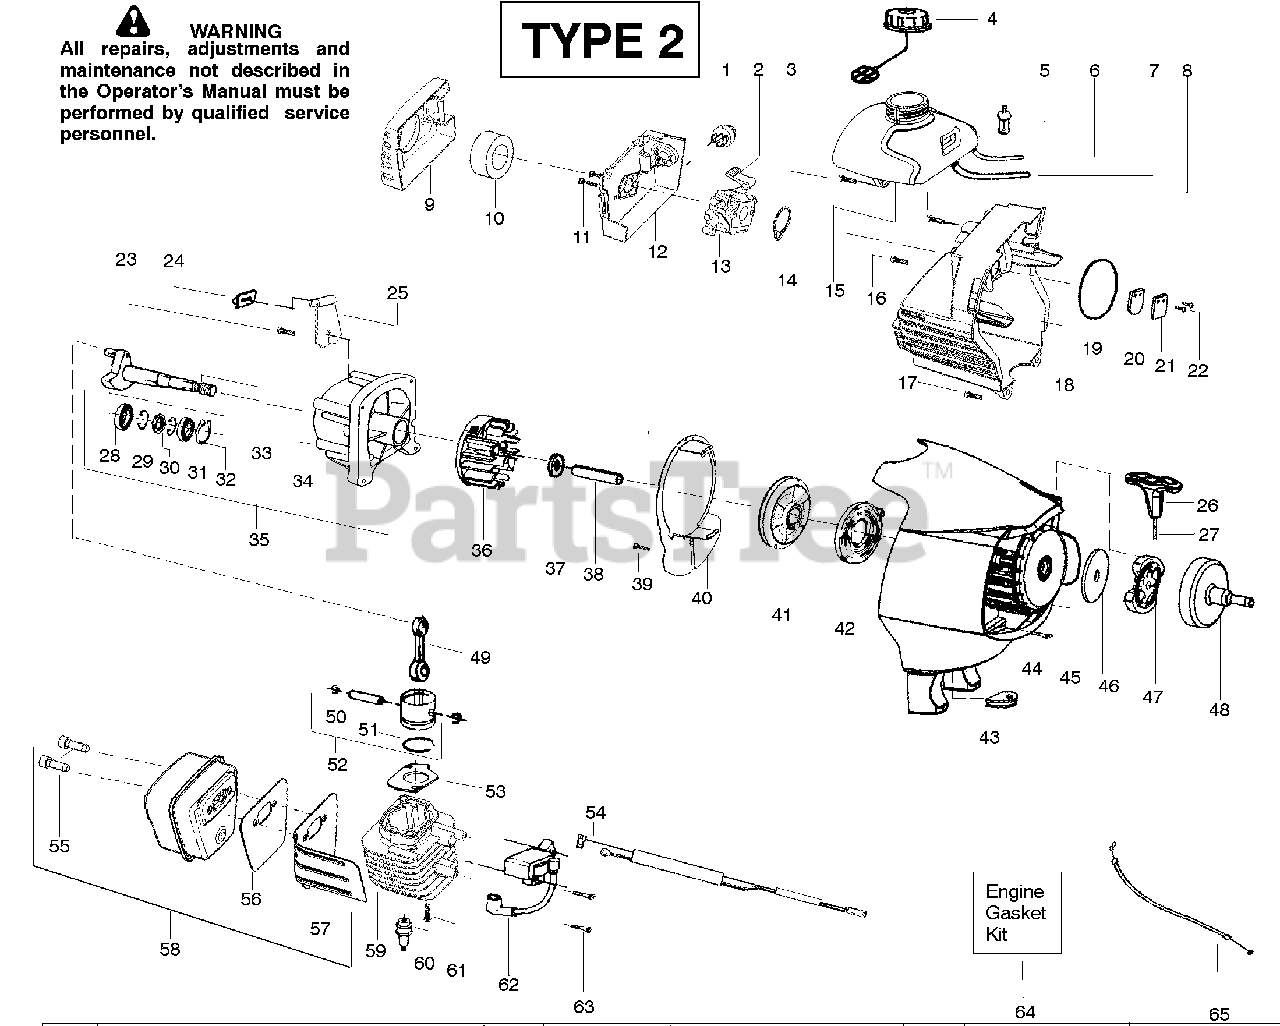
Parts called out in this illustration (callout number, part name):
2	Kit-Choke Lever
4	Cap-Fuel w/ret.
5	Assy-Fuel pickup
6	Kit-Fuel line
7	Kit-Fuel/Purge line
9	Cover-Air box
13	Kit-Carb assy. (C1U-W32)
14	Seal-Carb.(kit)
15	Assy-Fuel Tank
16	Screw-Crankcase
18	Assy-Rear Shroud
19	O-ring-Shroud (kit)
22	Screw-Reed stop
23	Screw-Retainer
24	Isolator-Tank
26	Handle-Starter
27	Kit-Rope
28	Bearing-Inner
31	Bearing-Outer
32	Ret.-Crankshaft
33	Assy-Crankshaft
34	Assy-Crankcase
35	Assy-C'case/C'shaft
36	Assy-Flywheel
40	Plate-Baffle
42	Spring-Starter
44	Screw-F/hsg.
45	Assy-Fan Housing
46	Washer-Clutch
48	Assy-Drum/Adapter
49	Assy-Conn. Rod
50	Ret.-Piston pin
53	Gasket-Cylinder(kit)
54	Assy-Leadwire
55	Bolt-Muffler 1/4"-20
57	Kit-Spark Arrestor
58	Gasket-Muffler (kit)
60	Kit-Muffler
62	Plug-Spark(RCJ-6Y)
63	Bolt-Cyl. 1/4"-20
64	Module-Ignition
66	Kit-Gasket/Seal
67	Assy-Throttle cable
